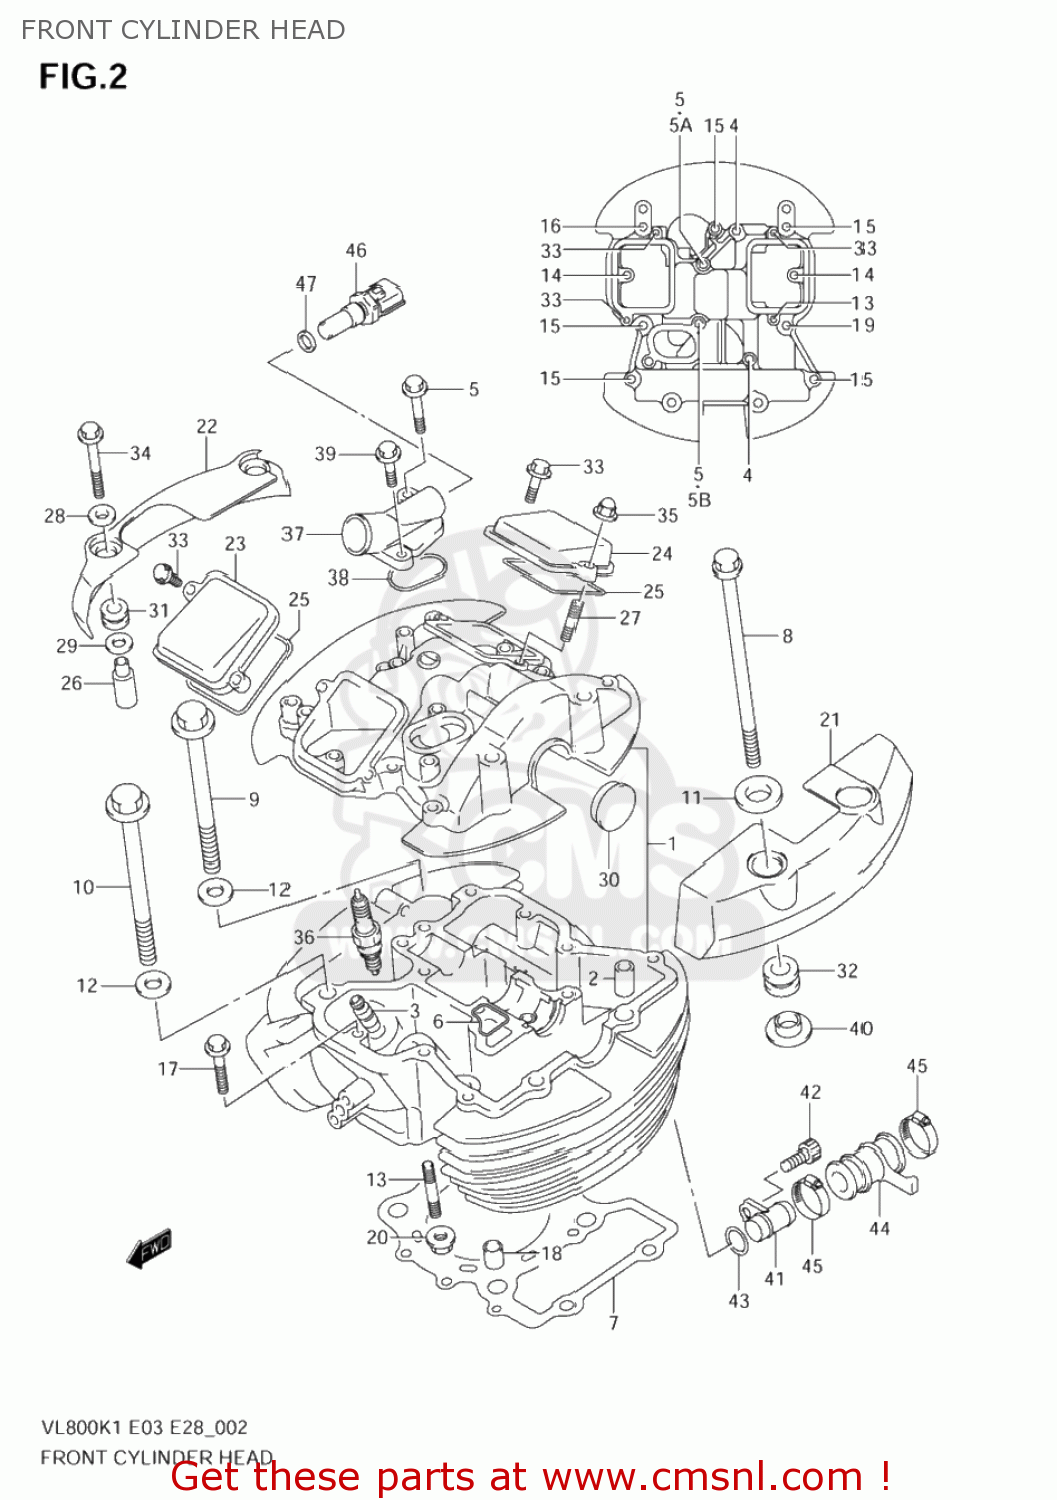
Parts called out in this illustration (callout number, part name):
1	HEAD ASSY,CYLINDER FR
2	PIN(8.4X11X14)
3	GUIDE,VALVE
4	BOLT(6X50)
5	BOLT(6X55)
5A	BOLT(6X55)
5B	BOLT
6	GASKET,CYLINDER HEAD WATER (NAS)
7	GASKET,CYLINDER HEAD FR (NAS)
8	BOLT(8X250)
9	BOLT(10X155)
10	BOLT(10X165)
11	WASHER(8.5X24X1.6)
12	WASHER(10.5X22X2.3)
13	TAPEIND
14	BOLT
15	BOLT
16	BOLT
17	BOLT
18	PIN
19	BOLT
20	NUT
21	CAP,CYLINDER HEAD COVER FL
22	CAP,CYLINDER HEAD COVER FR
23	CAP,INSPECTION INTAKE
24	CAP,INSPECTION EXHAUST
25	GASKET,INSPECTION CAP (NAS)
26	SPACER,CYL HEAD COVER CAP NO.2
27	BOLT,STUD
28	WASHER(6.5X18X1.6)
29	WASHER(9.5X20X1)
30	PLUG(OD:30)
31	CUSHION
32	CUSHION
33	SCREW
34	BOLT
35	NUT
36	SPARK PLUG X22E
37	UNION,WATER OUTLET
38	GASKET,WATER OUTLET UNION (NAS)
39	BOLT
40	BUSH
41	UNION,CYL HEAD
42	BOLT,STRANGER
43	O RING(D:2.4,ID:15.8)
44	HOSE,CYL HEAD
45	CLAMP
46	SENSOR,WATER TEMP
47	GASKET(12X17X1) (NAS)
